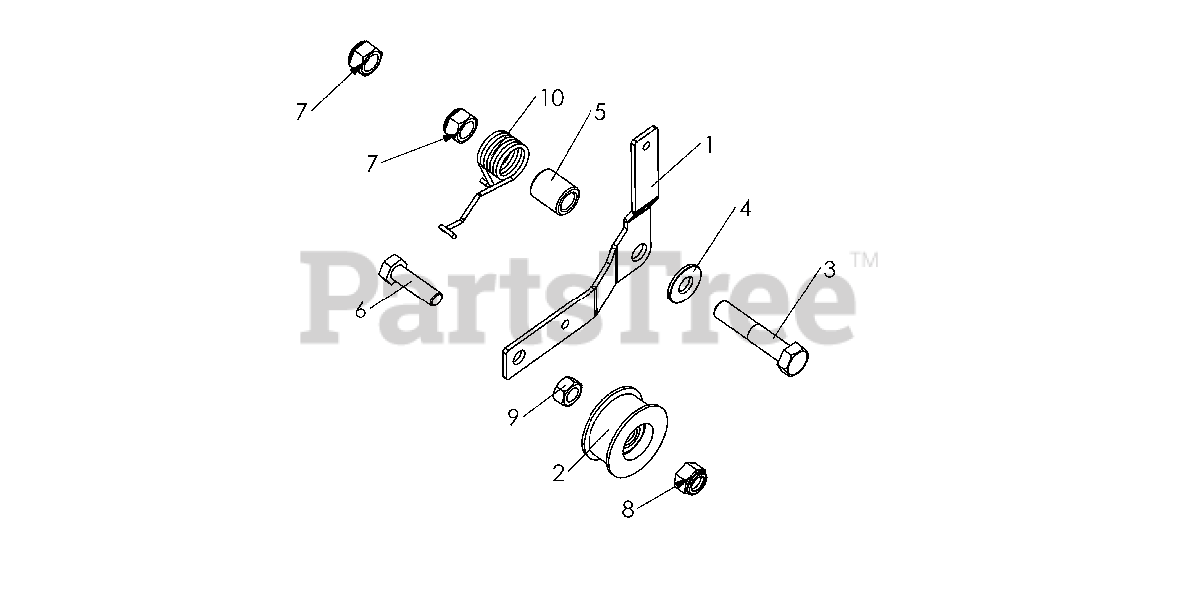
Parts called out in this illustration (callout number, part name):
2	PULLEY
4	WASHER
6	SCREW
8	NUT
9	NUT
10	SPRING
